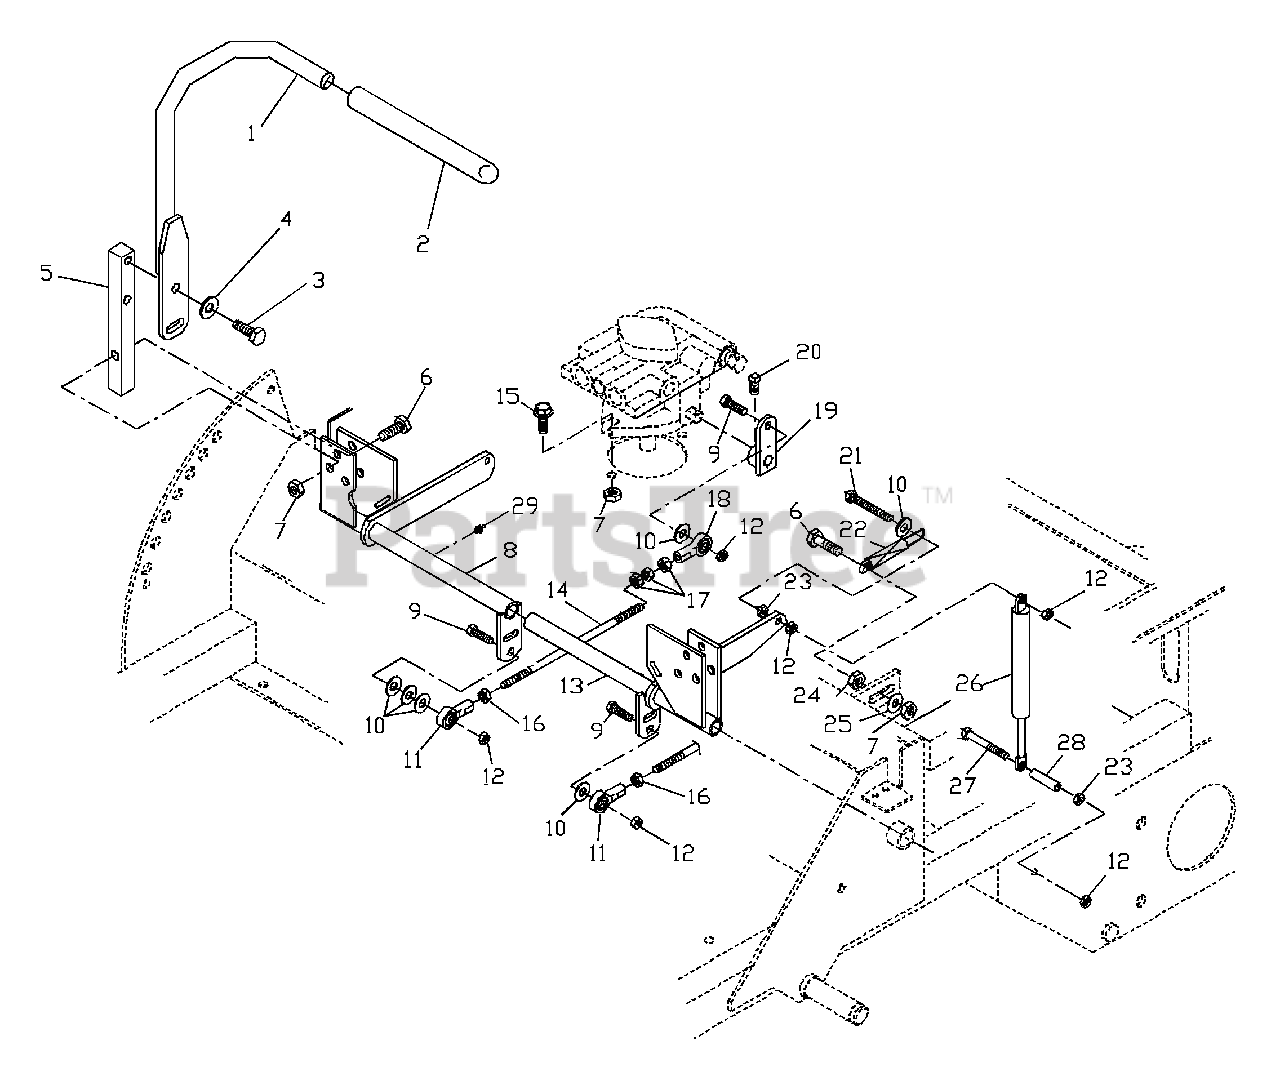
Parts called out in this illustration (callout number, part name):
1	CONTROL LEVER WLDMT
3	HCS 3/8C X 1
4	3/8 DISC SPRING WASHER
5	CONTROL ARM
6	HCS 3/8C X 1 1/2
7	NUT 3/8C CENTERLOCK
8	CONTROL WELDMENT, RIGHT
9	HCS 5/16C X 1 1/4
10	WASHER 5/16 FLAT
11	BALL JOINT, LEFT HANDED
12	NUT 5/16C CENTERLOCK
13	CONTROL WELDMENT, LEFT
14	PUMP CONTROL LINK
15	HCS 3/8C X 1 SERRATED HEAD
16	NUT 5/16F LEFTHAND
18	BALL JOINT, RIGHTHAND
19	CONTROL ARM, PUMP
20	5/16C X 5/8 SQ. HEAD
21	TAPBOLT 5/16C X 2 1/4
23	5/16C WHIZ NUT
24	3/8C WHIZ NUT
25	WASHER 3/8 FLAT
27	HCS 5/16C X 2 3/4 GRADE 8
29	ZERK
